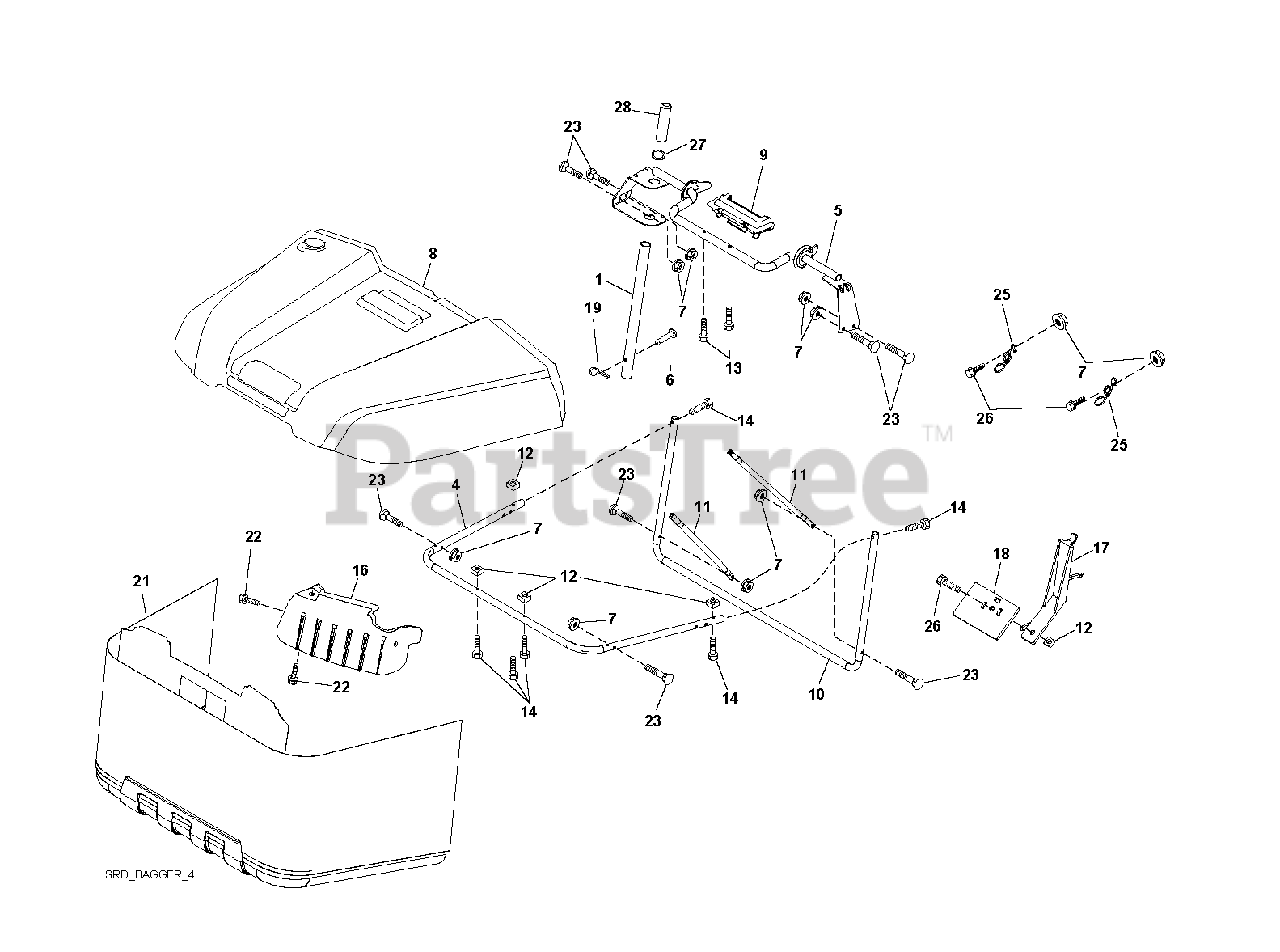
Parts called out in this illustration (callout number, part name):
1	TUBE.PNT.HDL.BAGGER.
6	RIVET,DRILLED
7	NUT T
19	PIN.COTTER.5/16.BOW TI
22	SCREW.HI-LO.CONSOLE
26	SCREW HEX CRT
28	GRIP.HANDLE.BLACK
